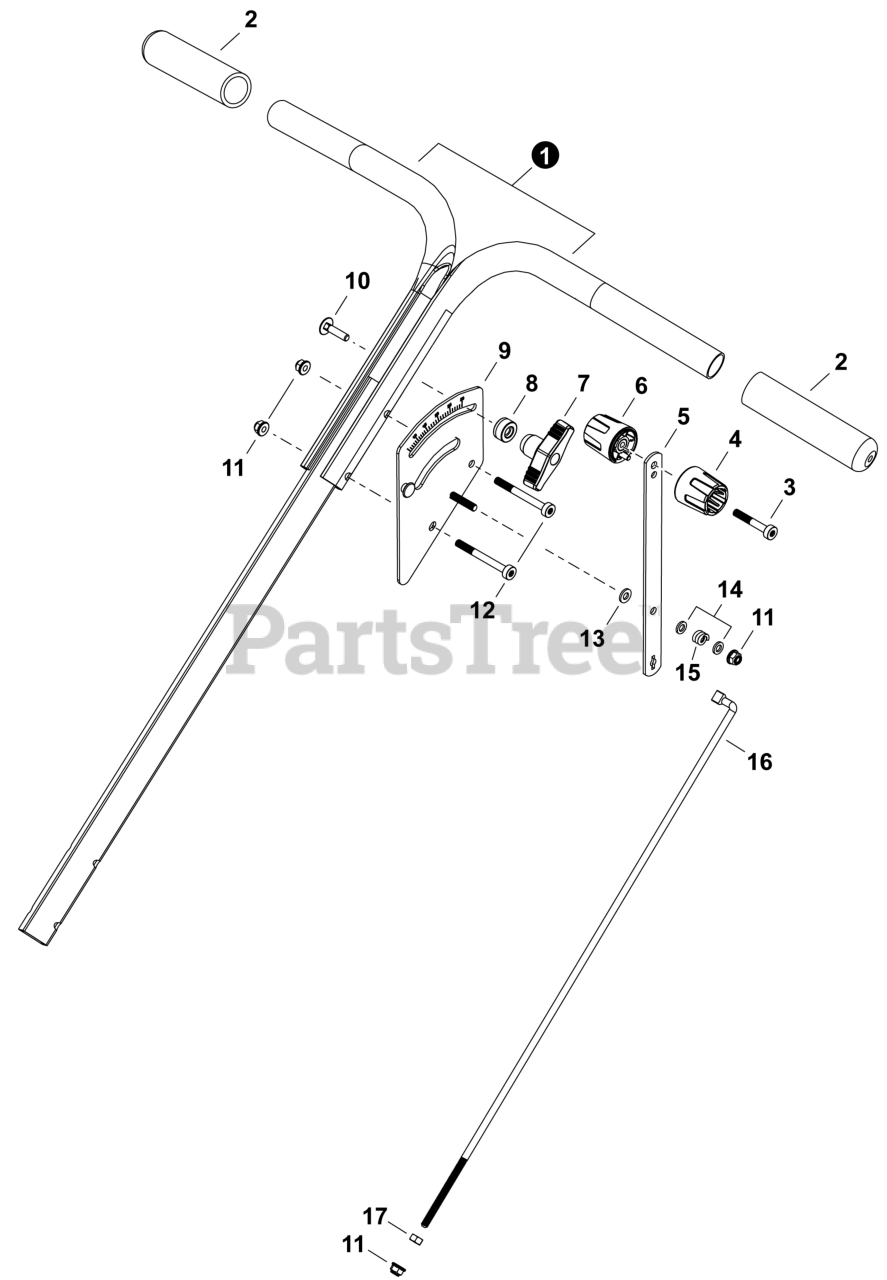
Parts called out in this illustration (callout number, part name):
2	GRIP, HANDLE
3	BOLT 6x40
4	KNOB, REGULATOR - LEFT
5	LEVER, REGULATOR
6	KNOB, REGULATOR - RIGHT
7	THUMBSCREW
9	BRACKET, REGULATOR
10	BOLT M6 x 26MM
11	NUT, FLANGE M6
12	BOLT, M6 X 60MM
14	WASHER 6
15	SPRING, COMPRESSION
16	ROD, REGULATOR
17	NUT, HEX M6
